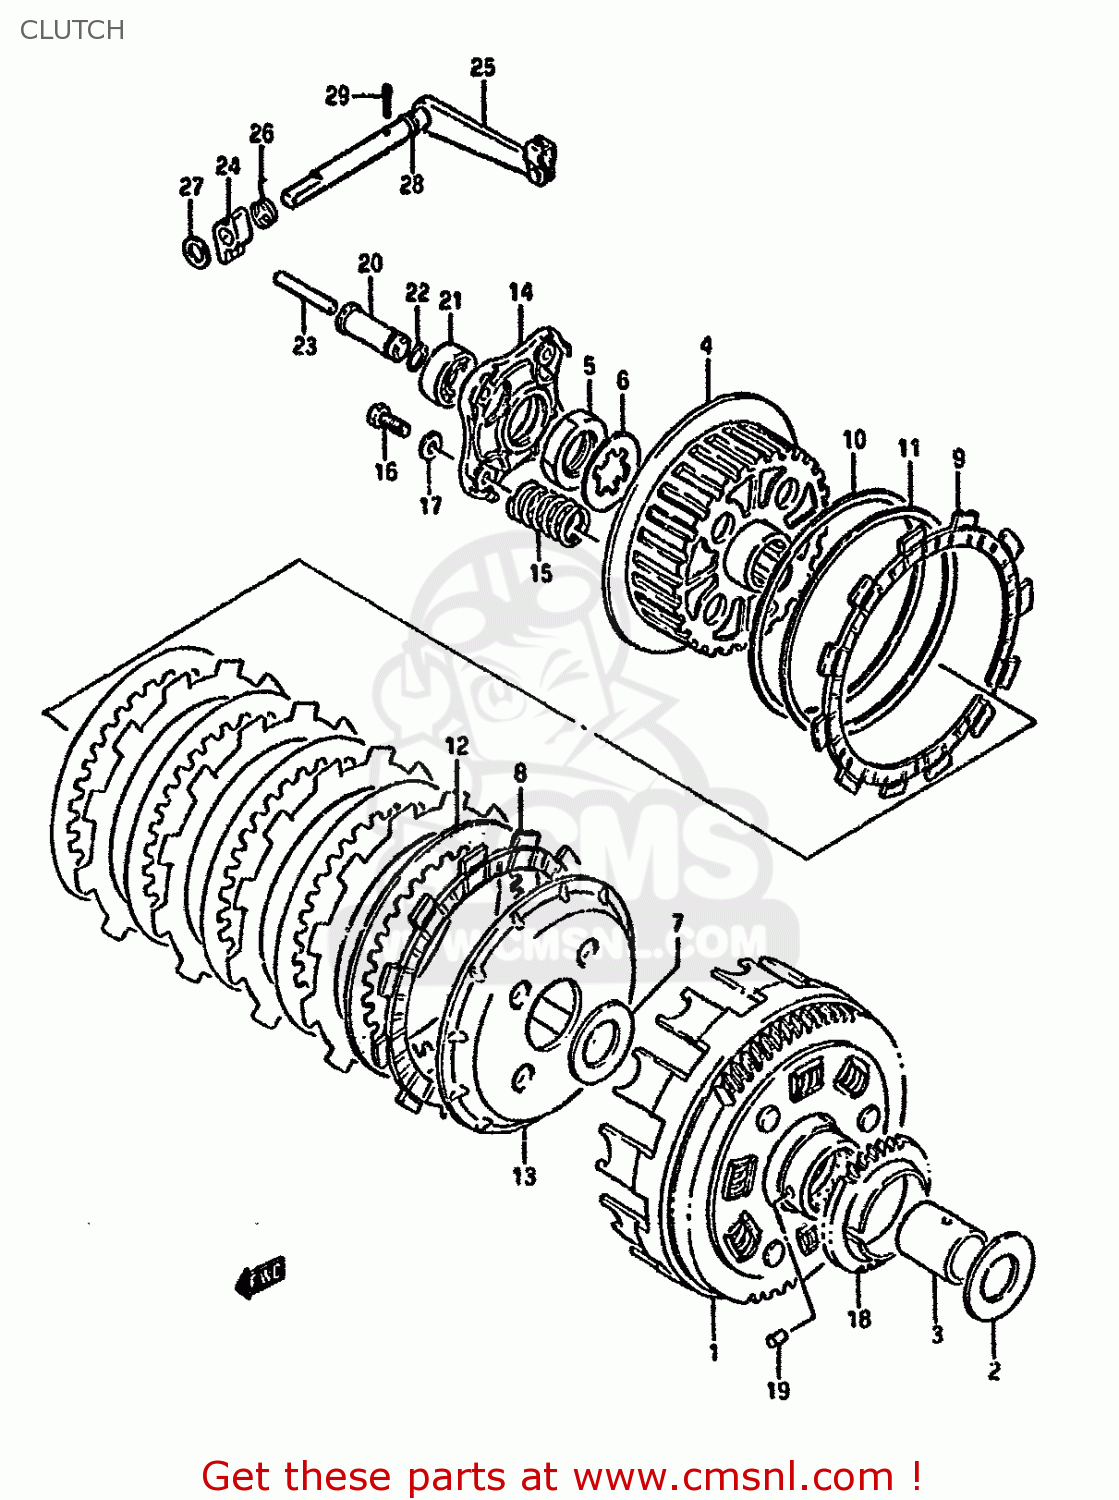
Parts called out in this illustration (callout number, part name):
1	GEAR ASSEMBLY,PRIMARY DRIVE
2	WASHER
3	SPACER(22X28X32.5)
4	HUB,CLUTCH SLEEVE
5	NUT
6	WASHER,LOCK
7	WASHER
8	PLATE,CLUTCH DRIVE (NAS)
9	PLATE,CLUTCH DRIVE(T:3.5) (NAS)
10	SEAT,WAVE WASHER(T:1.4)
11	WASHER
12	PLATE,CLUTCH DRIVEN(T:1.6) (NAS)
13	DISC,CLUTCH PRESSURE
14	PLATE,RELEASE
15	SPRING
16	BOLT
17	WASHER
18	GEAR,ENG OIL PUMP DRIVE
19	PIN(6X6)
20	PIECE,CLUTCH PUSH
21	BEARING
22	O RING(D:1.9,ID:8.6)
23	ROD,CLUTCH PUSH
24	CAM,CLUTCH RELEASE
25	ARM ASSY,CLUTCH RELEASE
26	SPRING
27	WASHER,THRUST
28	O RING(D:1.9,ID:6.8)
29	PIN 20X20
